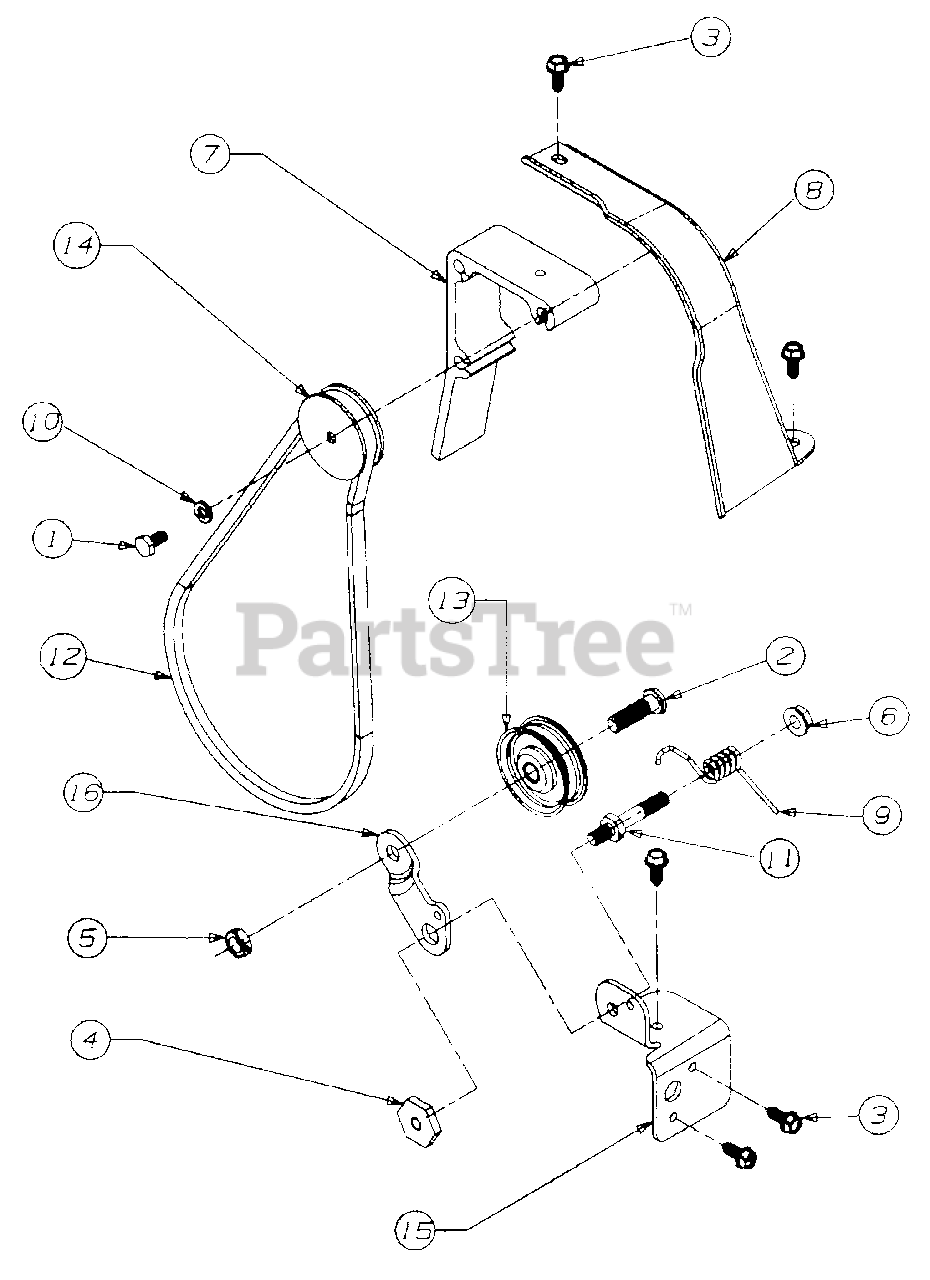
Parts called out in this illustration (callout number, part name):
1	SCREW - HEX
2	SCREW - HEX
3	SCREW - HEX
4	NUT - HEX SHOULDER
5	NUT - HEX LOCK
6	NUT - HEX LOCK FLANGE
7	ADAPTER - MOUNTING
10	WASHER - LOCK
11	BOLT - IDLER
12	V-BELT
13	IDLER - FLAT
14	PULLEY
